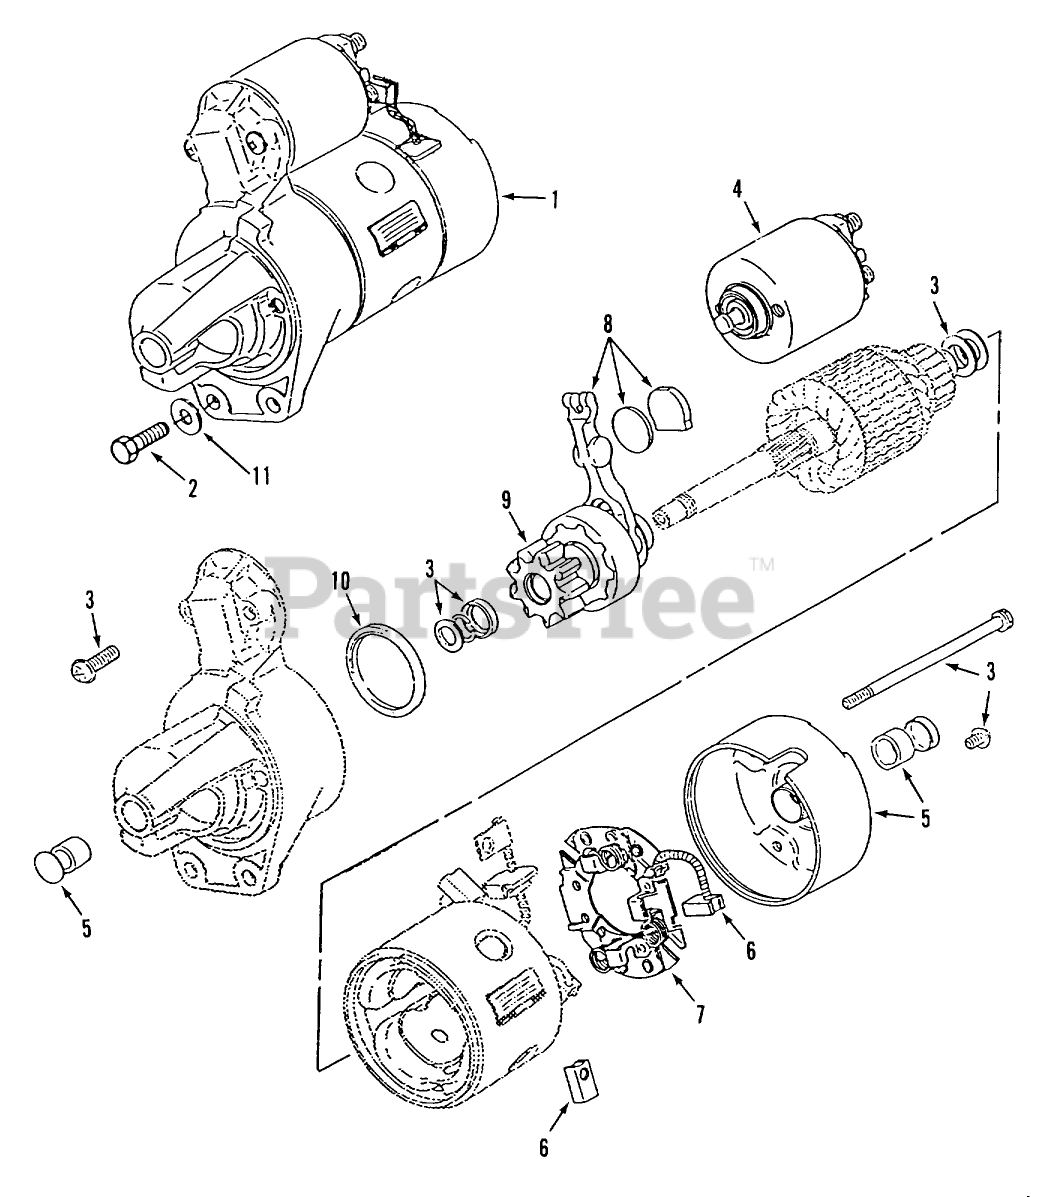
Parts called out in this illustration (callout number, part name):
1	Starter, Complete-see components below
2	Hex Hd. Cap Screw 5/16-18 x 1
3	Starter Hdwr. Kit (includes Solenoid Screws (2), Brush Holder Screws (2), Thru Bolts (2), Armature Shims (2), Pinion Stop Collar, and Pinion Retaining Ring)
4	Starter Solenoid Kit (includes Solenoid, Spring and Plunger)
5	Bushing Kit (includes Frt. Bushing and Rear Cap w/ Bushing)
6	Starter Brush Kit (includes Positive Brush (2) and Negative Brush w/ Pigtail)
7	Starter Brush Holder (includes Brush holder w/ Negative Brush)
8	Starter Shift Lever Kit (includes Shift Lever, Wear Plate and Rubber Plug)
9	Starter Clutch (includes Pinion Gear w/ Clutch)
10	Dust Seal
11	Washer
